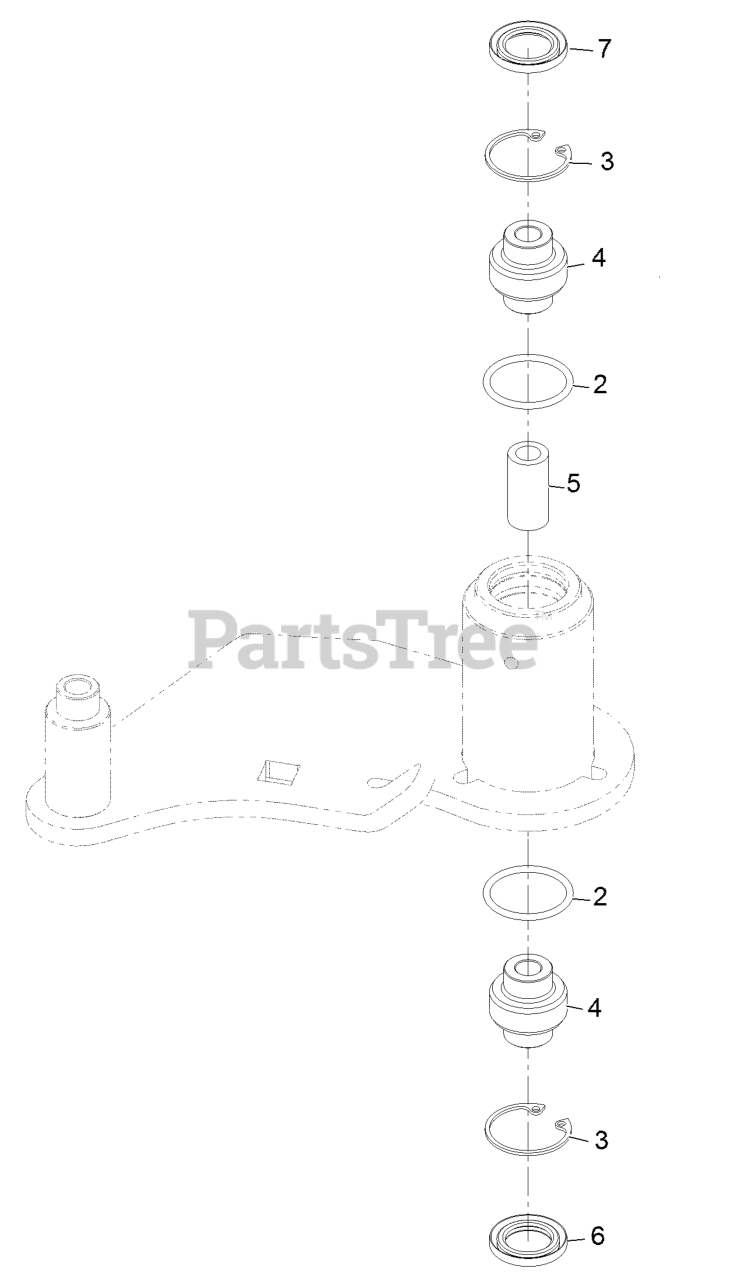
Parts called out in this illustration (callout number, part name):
3	RING-SNAP
4	BEARING-SPHERICAL
6	SEAL-LIP, DOUBLE
7	SEAL-LIP, SINGLE
